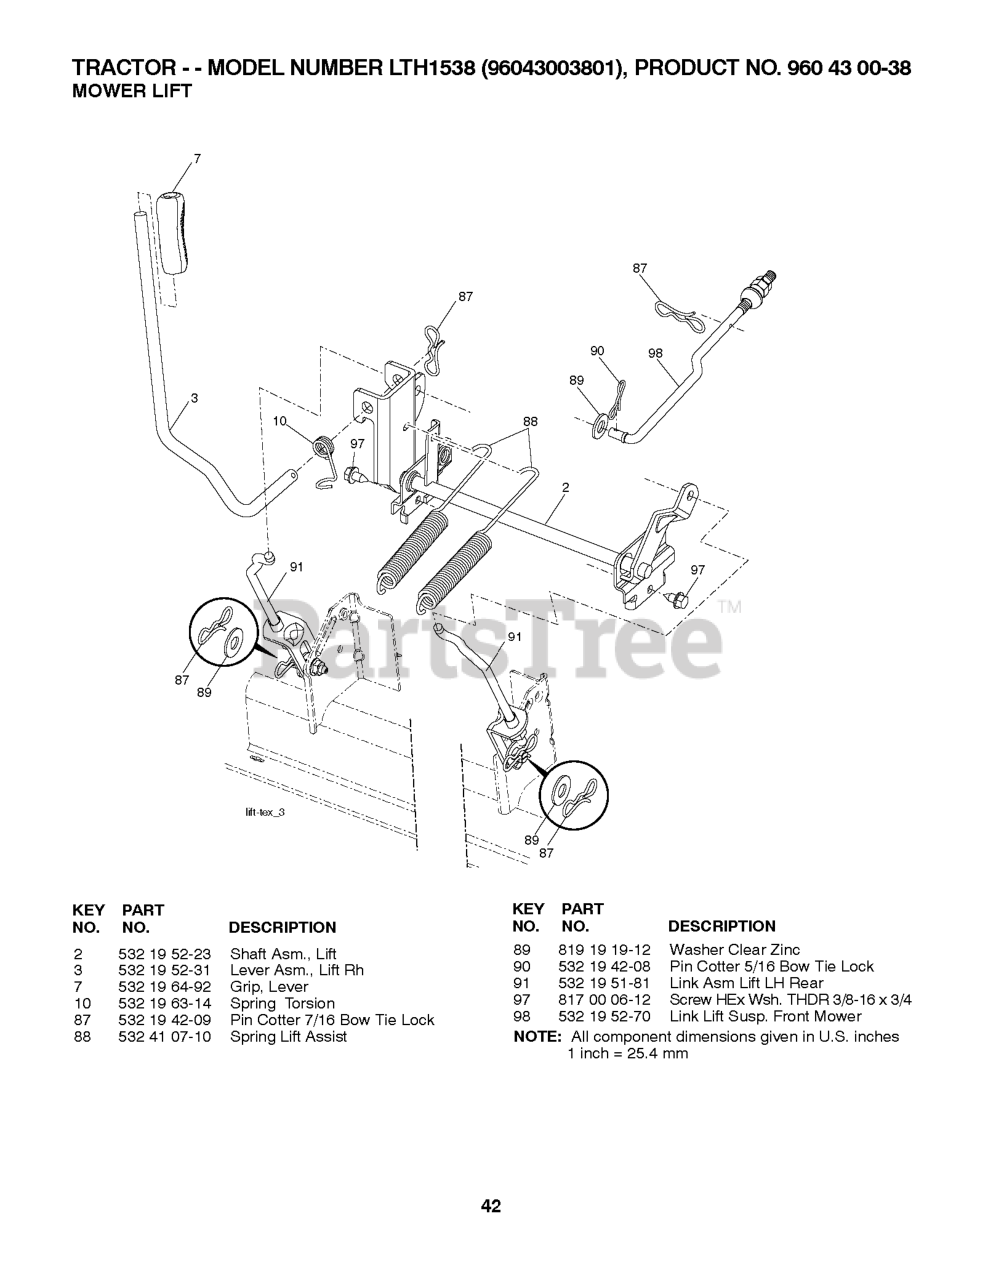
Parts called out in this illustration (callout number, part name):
2	SHAFT.ASM.LIFT.CROSS.H
3	LEVER.LIFT.HANDLE.LT
7	GRIP.LEVER.5625.ID
10	SPRING.TORSION.LIFT.HANDLE
87	PIN.COTTER.7/16.BOW TI.
88	SPRING.LIFT.ASSIST
89	WASHER.CLEAR.ZINC
90	PIN.COTTER.5/16.BOW TI
91	LINK.ASM.LIFT.REAR
97	SCREW, 3/8-16X3/4
98	LINK.ASM.SUSP.FRONT.MW
